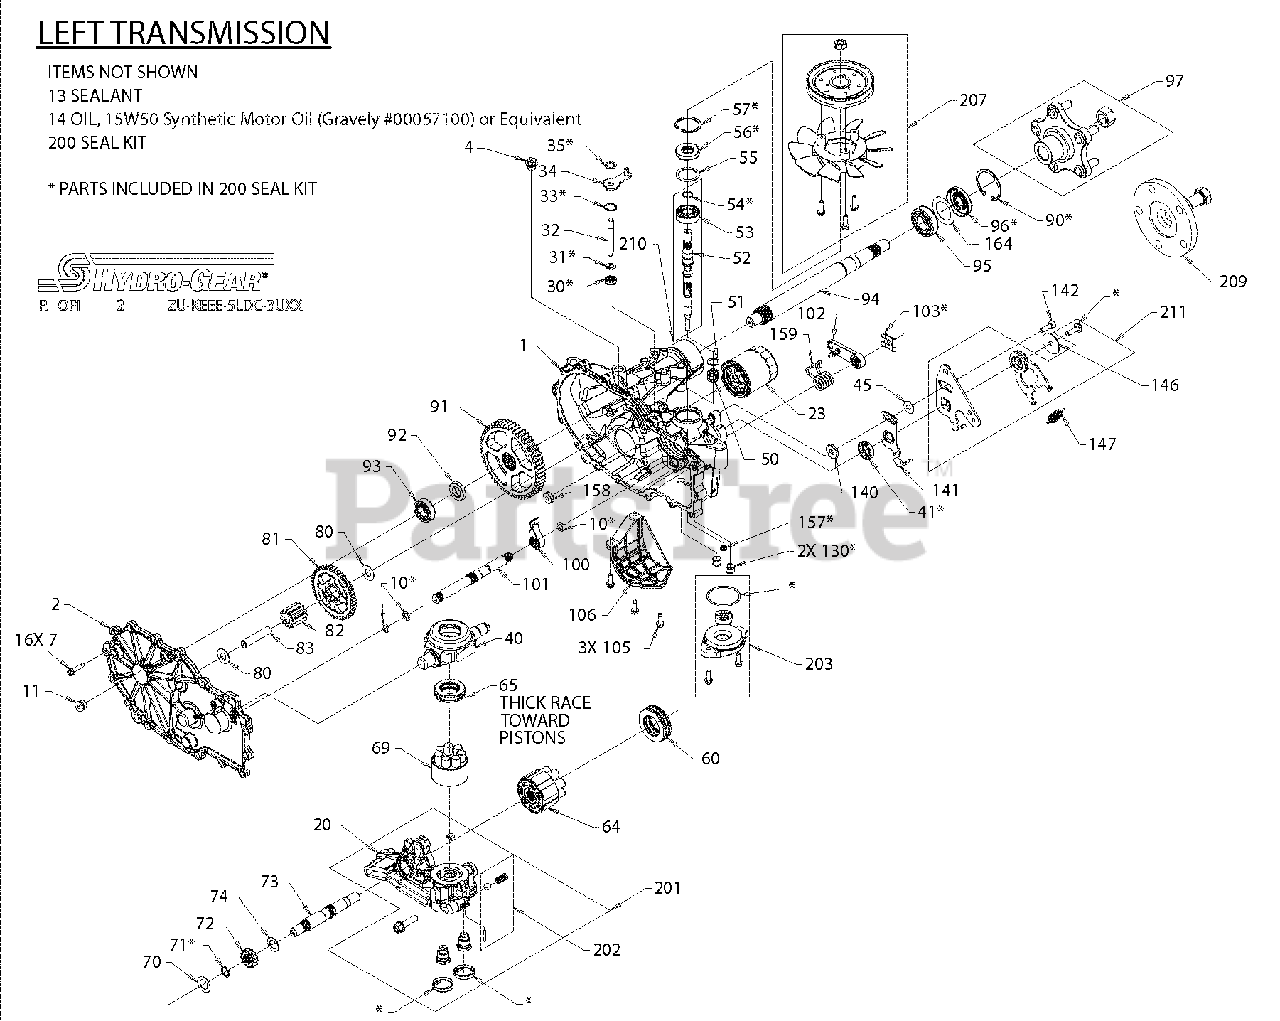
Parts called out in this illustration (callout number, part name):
7	HFHCS 1/4-20 X 1.25
13	SEALANT
23	FILTER, OIL
30	SEAL, LIP .375 X .75 X .25
31	RING, RET .375 EXTERNAL
33	RING, RET .750 INTERNAL
34	ARM, BYPASS
35	RING, RTNG .375 EXT
40	TRUNNION, SWASHPLATE
41	SEAL, LIP 18 X 32 X 7
45	WASHER .34 X .88 X .06
50	SPRING, BLOCK
51	WASHER-FLAT .59 x .79 x .04
55	WASHER 1.23 X 1.56 X .04
56	SEAL, LIP 17 X 40 X 7
57	RING, RET 2.06 INT
60	BEARING, THRUST
64	ASS'Y, CYLINDER BLOCK, 16cc
65	BRG, THRUST BALL 30 X 52 X 13
69	ASS'Y, BLOCK, 7 PISTON
70	WASHER .63 X 1.00 X .05
71	RING, RET .62 EXT
74	WASHER .72 X 1.16 X .04
80	WASHER .5 X 1.0 X .03
83	JACK SHAFT (PIN)
90	RING, RET 2.06 INT
95	BRG, BALL 1.0 x .52 x .15 OPEN 6205M
96	SEAL, LIP TC4 1.0 x 2.06 x .38
97	KIT, HUB, 5 BOLT
102	KIT, HANDLE ACTUATING
103	CLIP, RETAINING
105	SCREW, HEX FLANGE 1/4-2
140	SPACER .320 x 1.005 x .062
141	ARM, NEUTRAL LEFT
142	SHCS 5/16-24 x 1.00 (PATCH)
146	WASHER, .343 x 1.500 x .062
147	SPRING, EXTENSION RTN-34LBS
157	SEAL, LIP .281 x .420 x .16
158	MAGNET, RING
200	KIT, SEAL
201	KIT, CENTER SECTION, LH, CHRG
203	KIT, CHARGE PUMP
210	KIT, INPUT SHAFT
